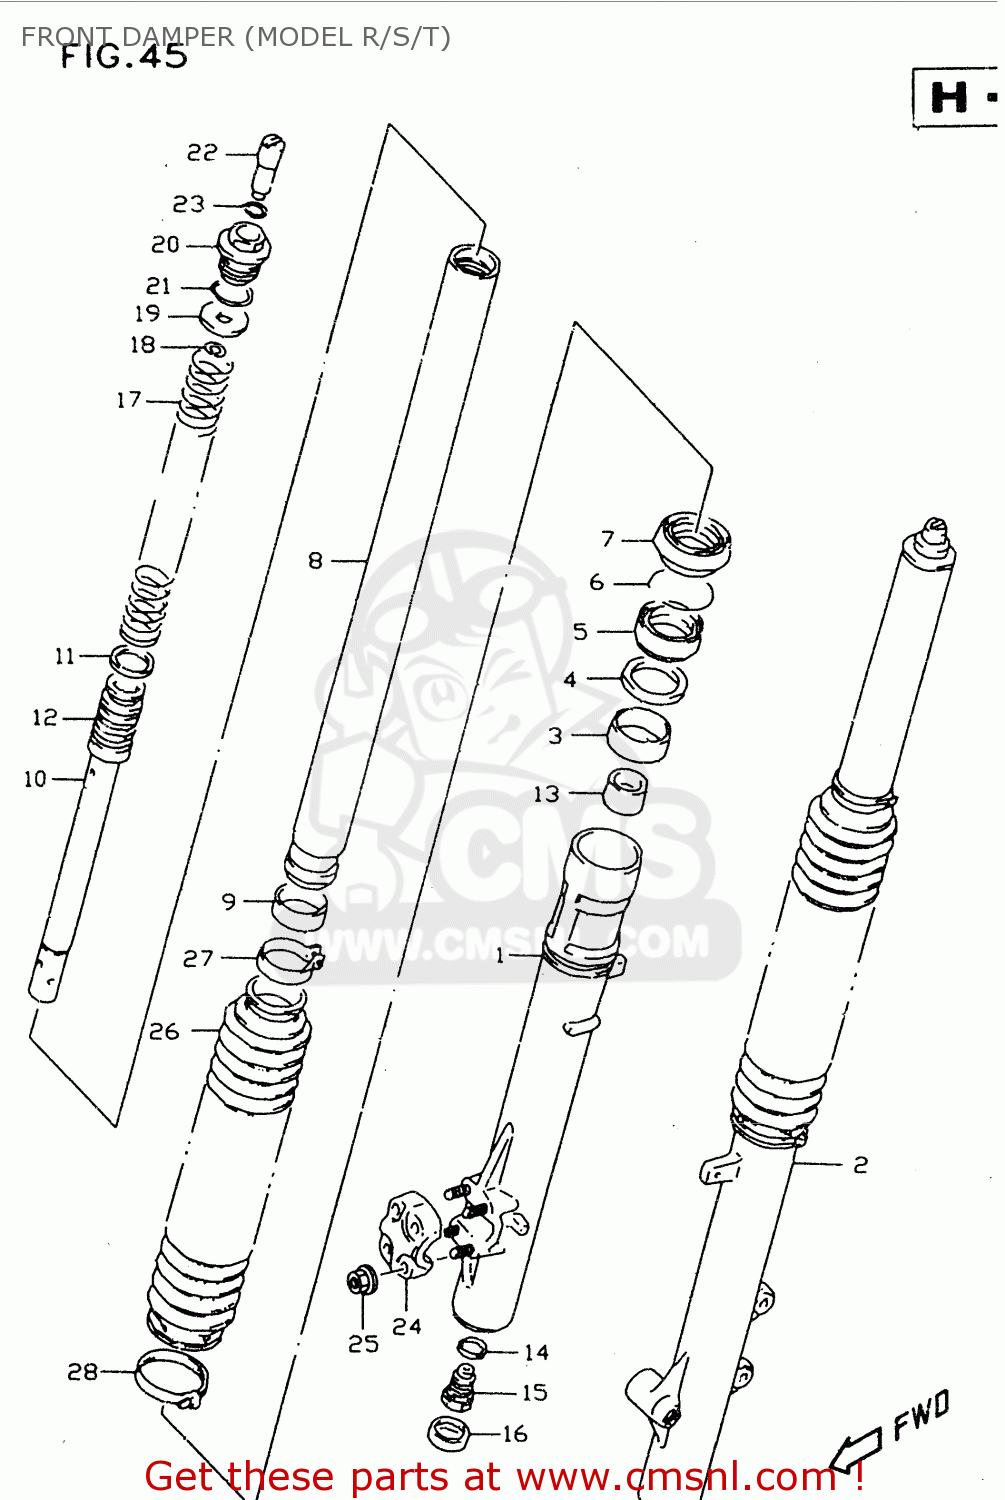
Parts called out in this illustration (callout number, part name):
1	TUBE,OUTER,R
2	TUBE,OUTER,L
3	BUSH,GUIDE
4	SPACER,SEAL
5	SEAL,OIL
6	CIRCLIP,FORK OIL SEAL
7	DUST SEAL
8	TUBE,INNER
9	BUSH,SLIDE
10	CYLINDER
11	RING,PISTON
12	SPRING,REBOUND
13	PIECE,OIL LOCK
14	GASKET (NAS)
15	BOLT,PIECE
16	CAP,LOWER
17	SPRING,MAIN
18	E RING
19	SEAT,SPRING
20	BOLT,FORK
21	O RING
22	ADJUSTER,SPRING
23	O RING
24	HOLDER,AXLE
25	NUT,HOLDER
26	BOOT
27	BAND,BOOT UPR
28	BAND,BOOT LWR
